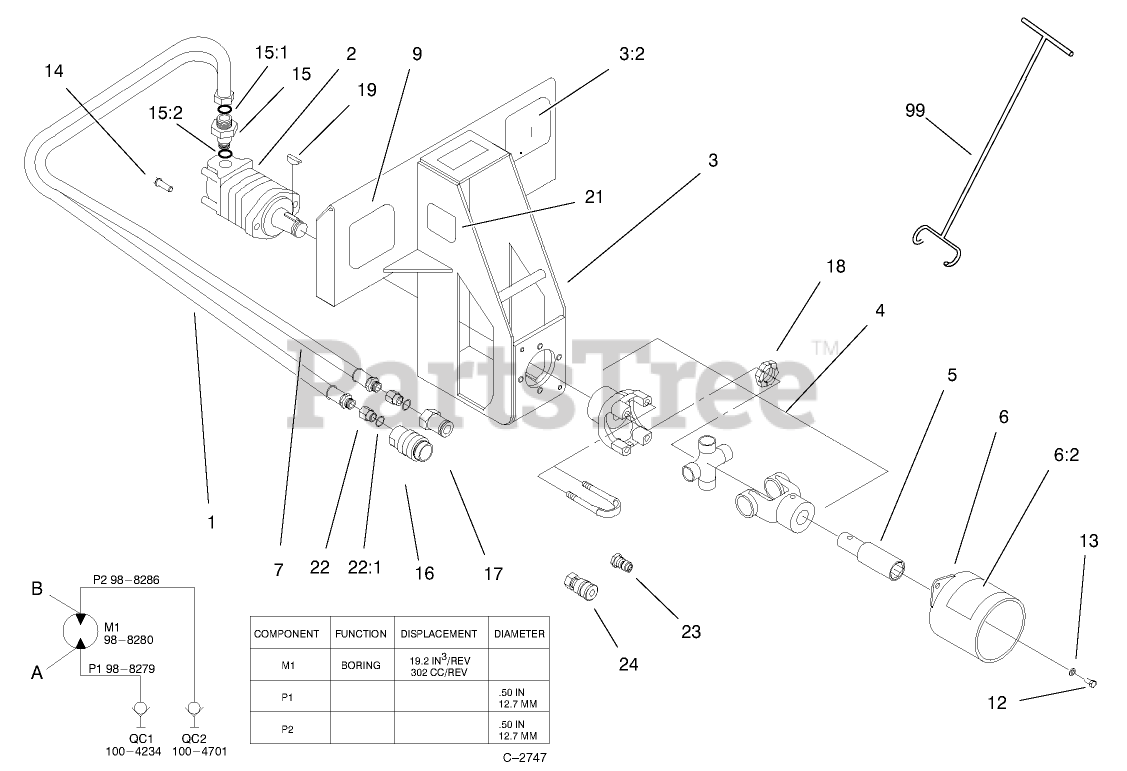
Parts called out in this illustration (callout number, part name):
1	HOSE - HYDRAULIC
2	MOTOR-HYDRAULIC
3	FRAME ASM
3:2	DECAL-WARNING
4	JOINT - UNIVERSAL
5	COUPLER - SPLINE
6	SHIELD ASM
6:2	DECAL-WARNING
7	HOSE - HYDRAULIC
9	DECAL-DINGO
12	SCREW-HH
13	WASHER-LOCK
14	SCREW
15	FITTING-STRAIGHT
15:1	O-RING
15:2	O-RING
16	COUPLER-FACE, FLUSH
17	NIPPLE-CONNECT, PRESSURE
18	NUT - SHAFT
19	KEY - SHAFT
21	DECAL
22	ADAPTER-HYD
22:1	O-RING
23	DISCONNECT-QUICK, MALE
24	DISCONNECT-QUICK, FEMALE
99	ROD GUIDE TOOL
